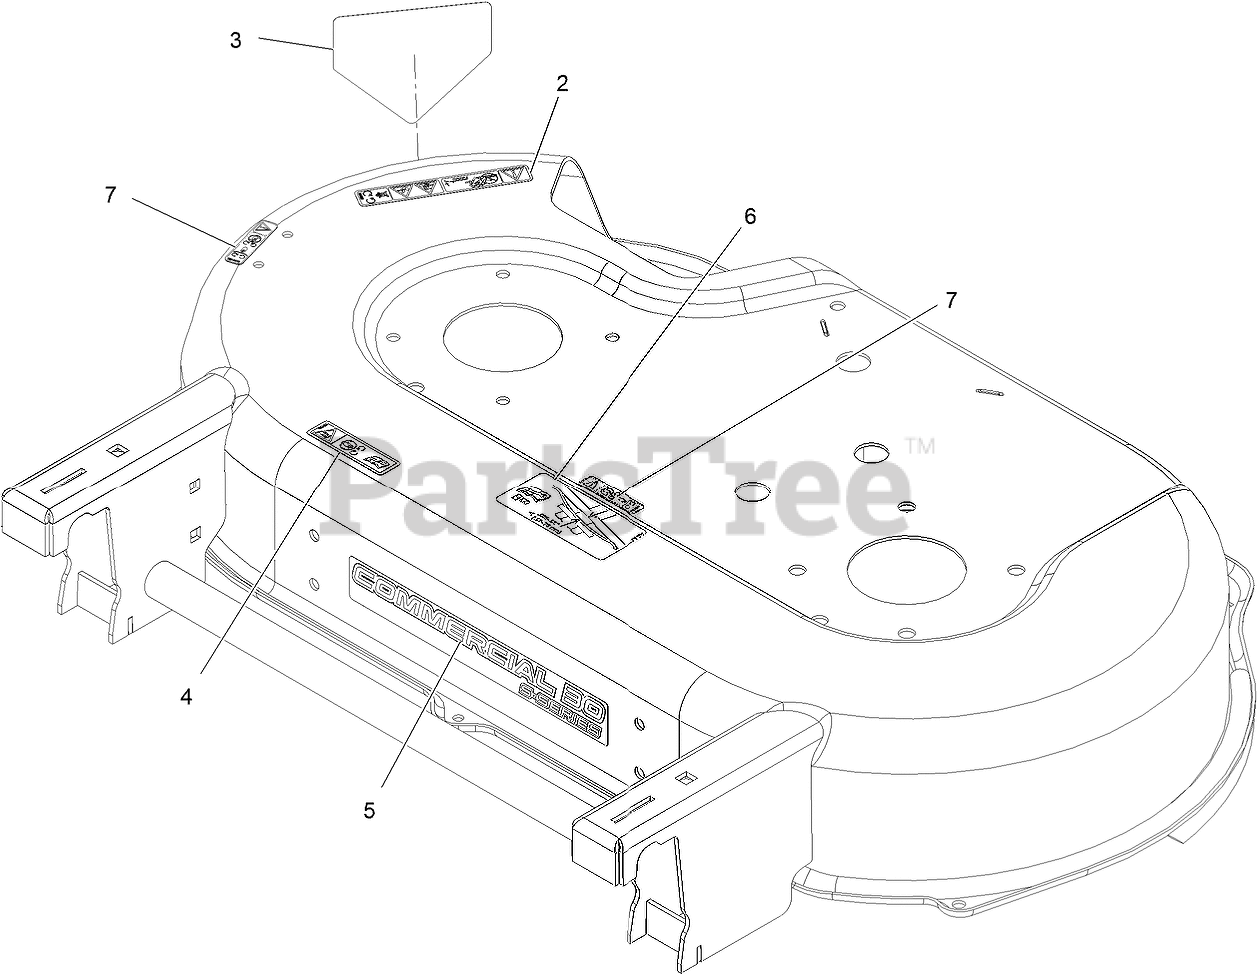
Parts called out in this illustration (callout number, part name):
2	DECAL-DANGER
3	DECAL-DANGER
4	DECAL-WARNING
5	DECAL-COMM 30 S-SERIES
7	DECAL-WARNING
